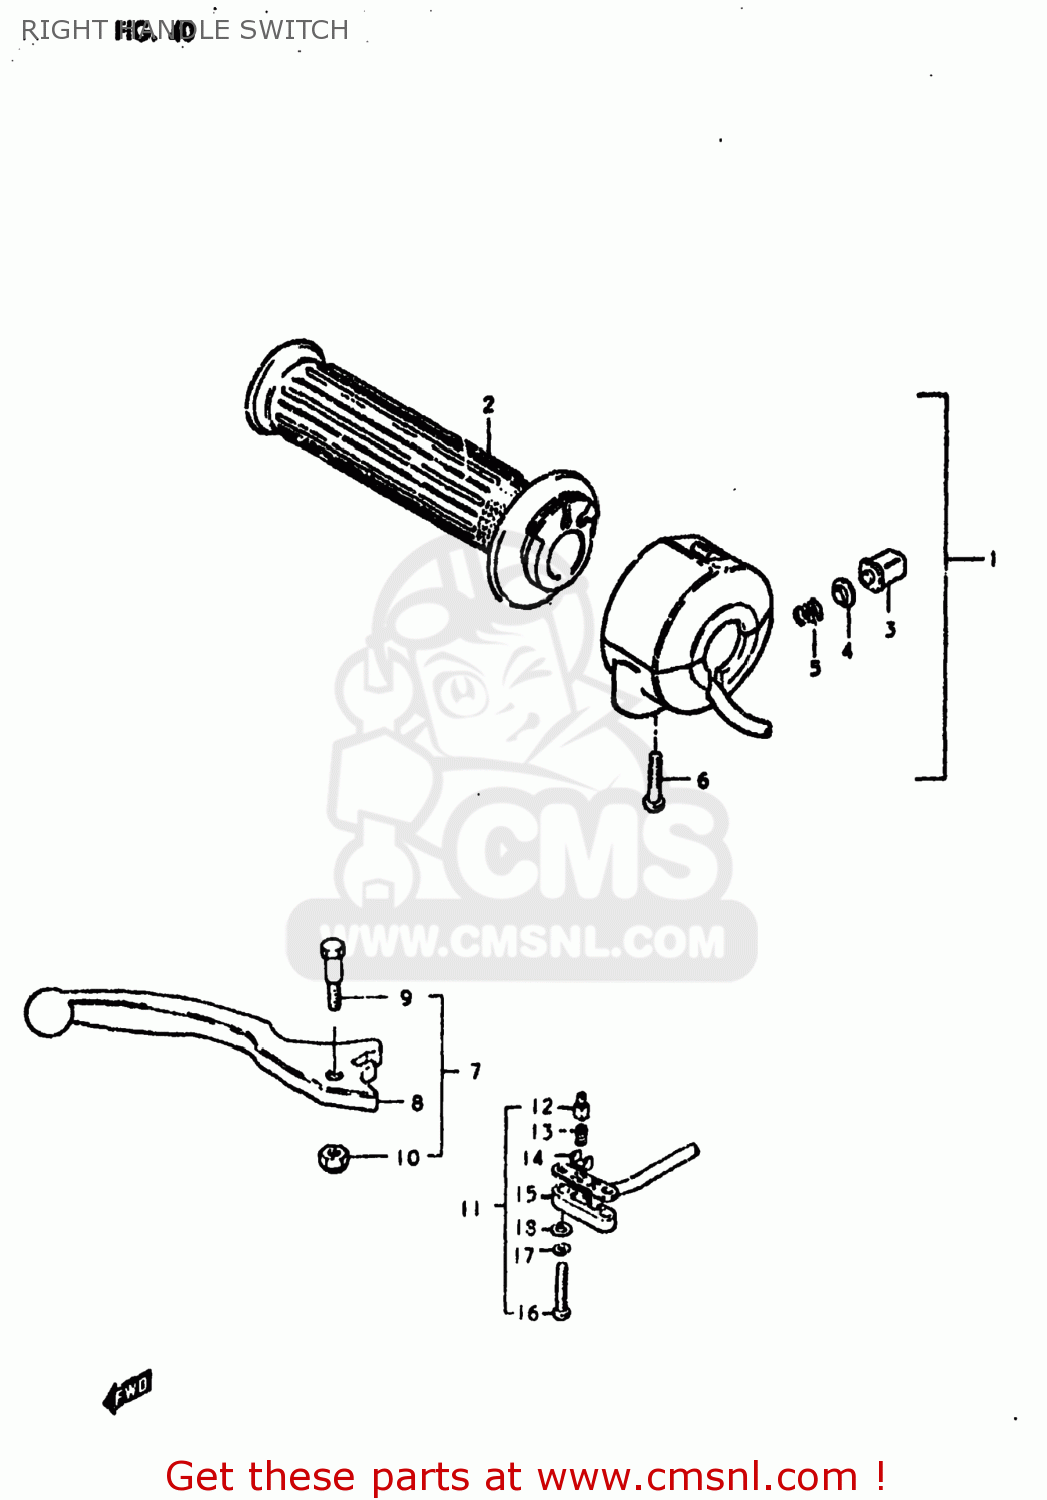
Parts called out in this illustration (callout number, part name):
1	CASE ASSEMBLY,THROTTLE
2	GRIP,THROTTLE
3	BUTTON,HORN
4	CONTACT
5	SPRING
6	SCREW
7	LEVER ASSEMBLY,BRAKE
8	LEVER,BRAKE
9	BOLT
10	NUT 6MM
11	SWITCH ASSEMBLY
12	HOLDER
13	SPRING
14	PLATE
15	COVER,FR BK TERMINAL BASE
16	SCREW
17	LOCK WASHER
18	WASHER
